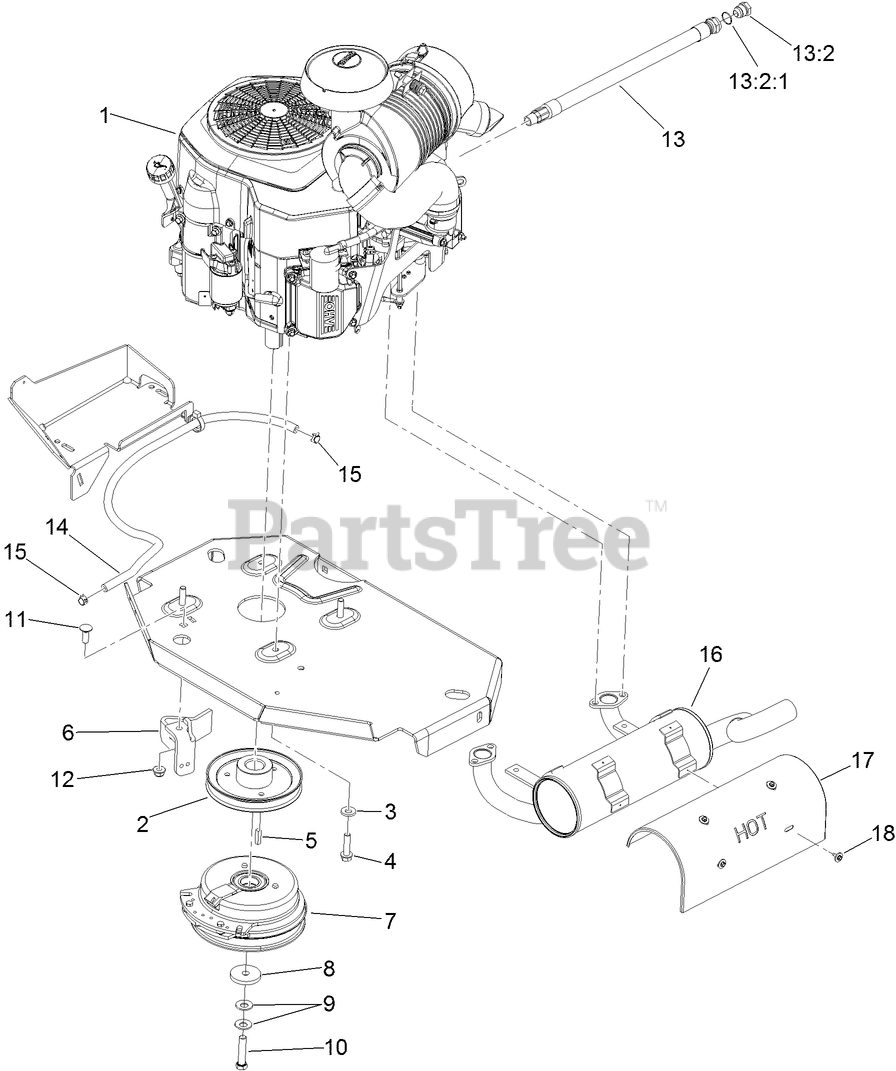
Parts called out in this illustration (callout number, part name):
2	SHEAVE
3	WASHER-BELLEVILLE
4	SCREW-HWH
6	CLUTCH-ANCHOR
7	CLUTCH KIT
8	WASHER-CLUTCH
9	WASHER-SPRING
10	SCREW-HH W/LOCTITE
11	SCREW-CARR
12	NUT-HF, NI
13	OIL DRAIN HOSE ASM
13:2	PLUG-HH
13:2:1	O-RING
14	HOSE-FUEL
15	CLAMP-HOSE
16	MUFFLER
17	GUARD-MUFFLER
18	SCREW-HH, THREAD FORMING
